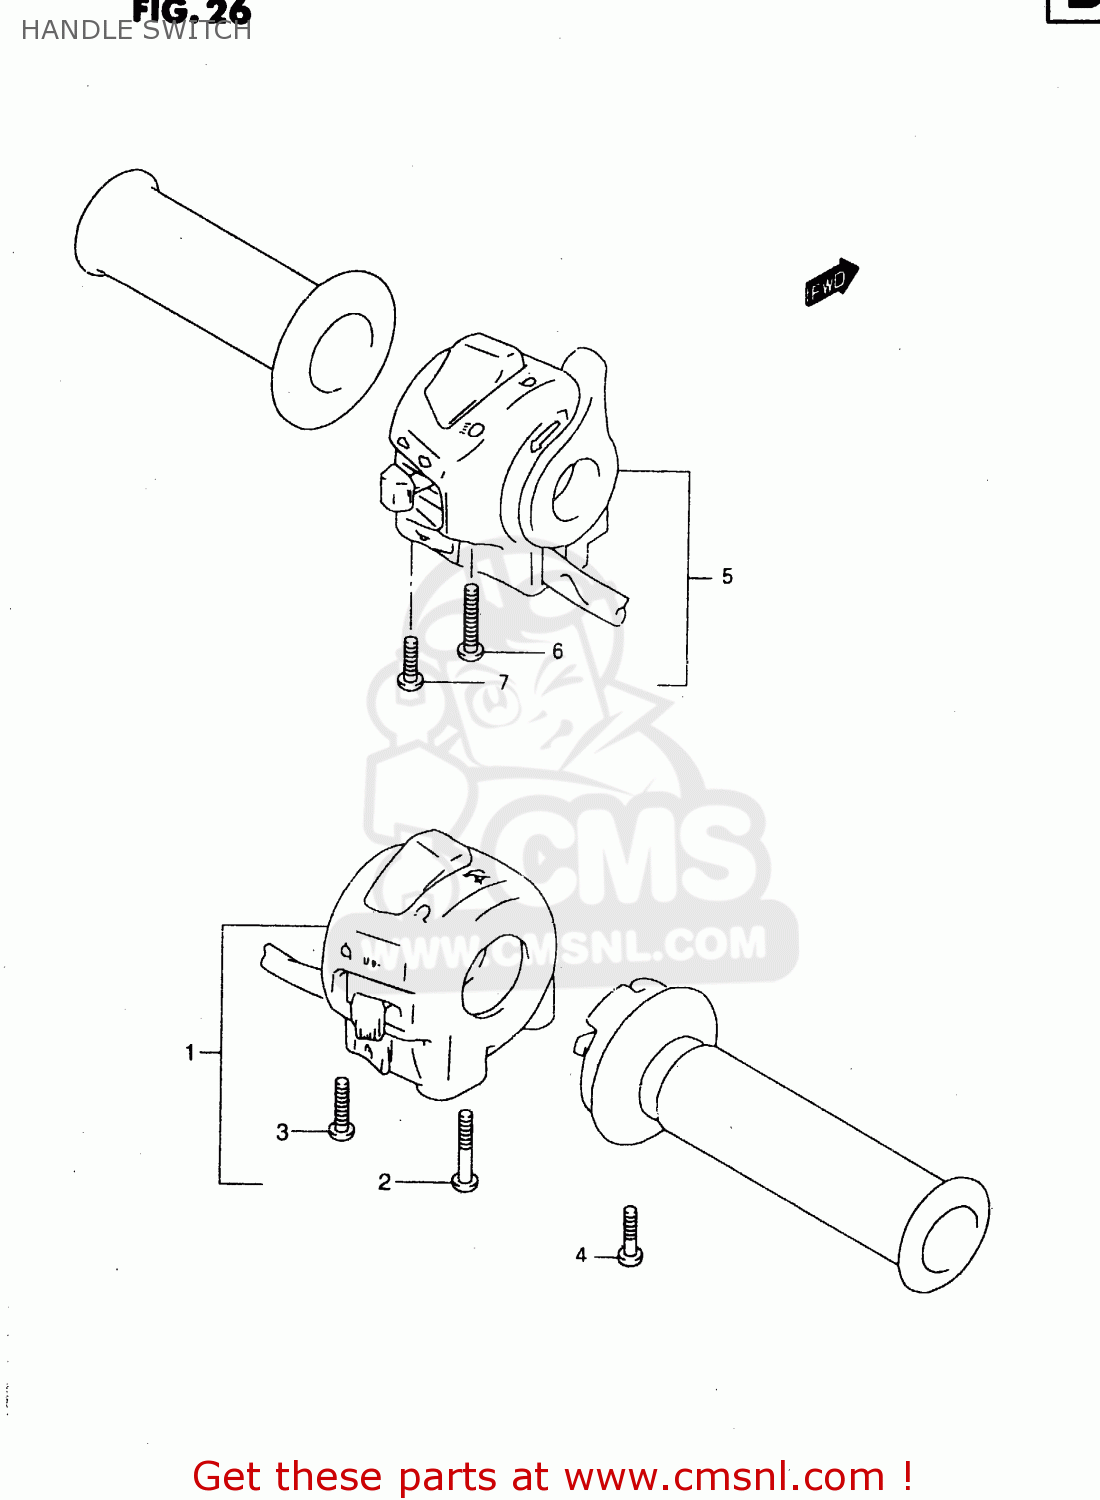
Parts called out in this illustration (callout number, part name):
1	SWITCH,HANDLE,
2	SCREW
3	SCREW
4	SCREW
5	SWITCH ASSY,HANDLE,L
6	SCREW
7	SCREW
